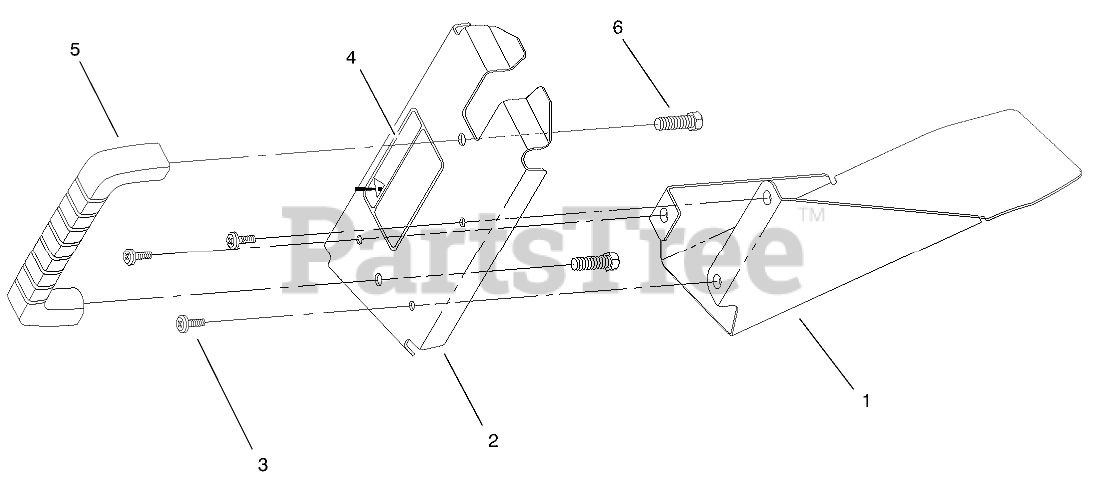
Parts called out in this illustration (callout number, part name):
1	Shield-Discharge Plug
2	Cover-Discharge Plug
4	DECAL - WARNING
5	HANDLE-DOOR
6	SCREW-HWH
